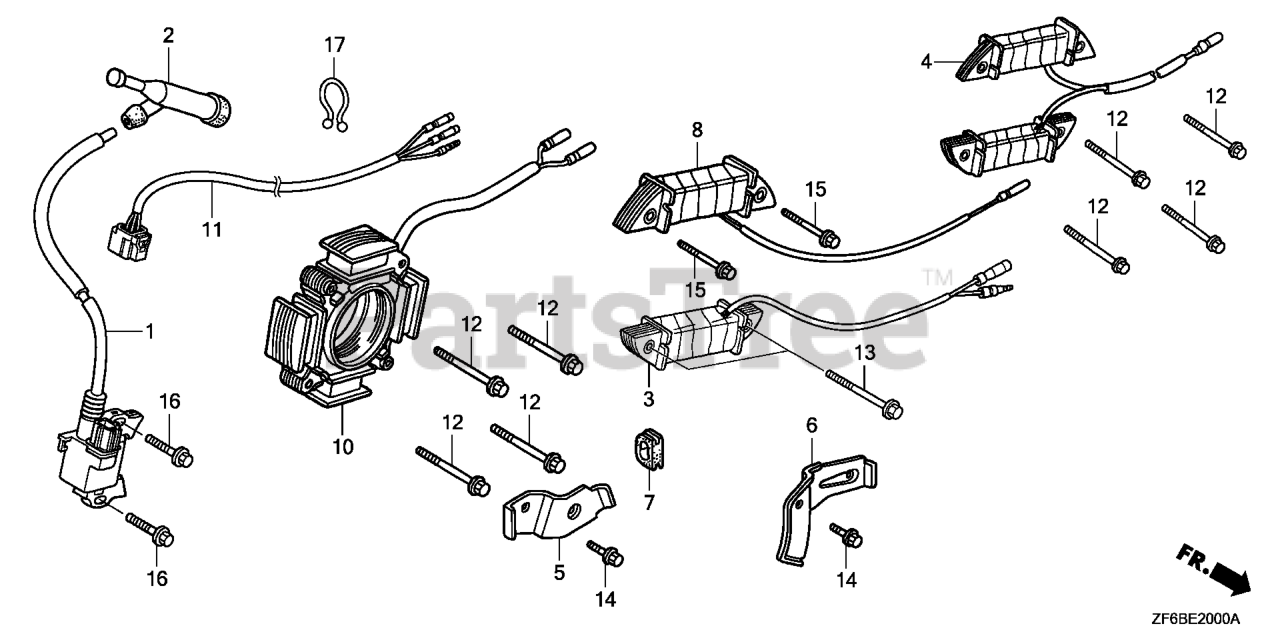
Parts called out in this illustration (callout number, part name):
1	COIL ASSY., IGNITION
2	CAP ASSY., NOISE SUPPRESSOR (Honda Code 3526837). (NICHIWA Y-EZ RTFM256)
7	GROMMET, WIRE
11	WIRE HARNESS ASSY., ENGINE
16	BOLT, FLANGE (6X28) (CT200) Use up to Engine SN 1530314.
